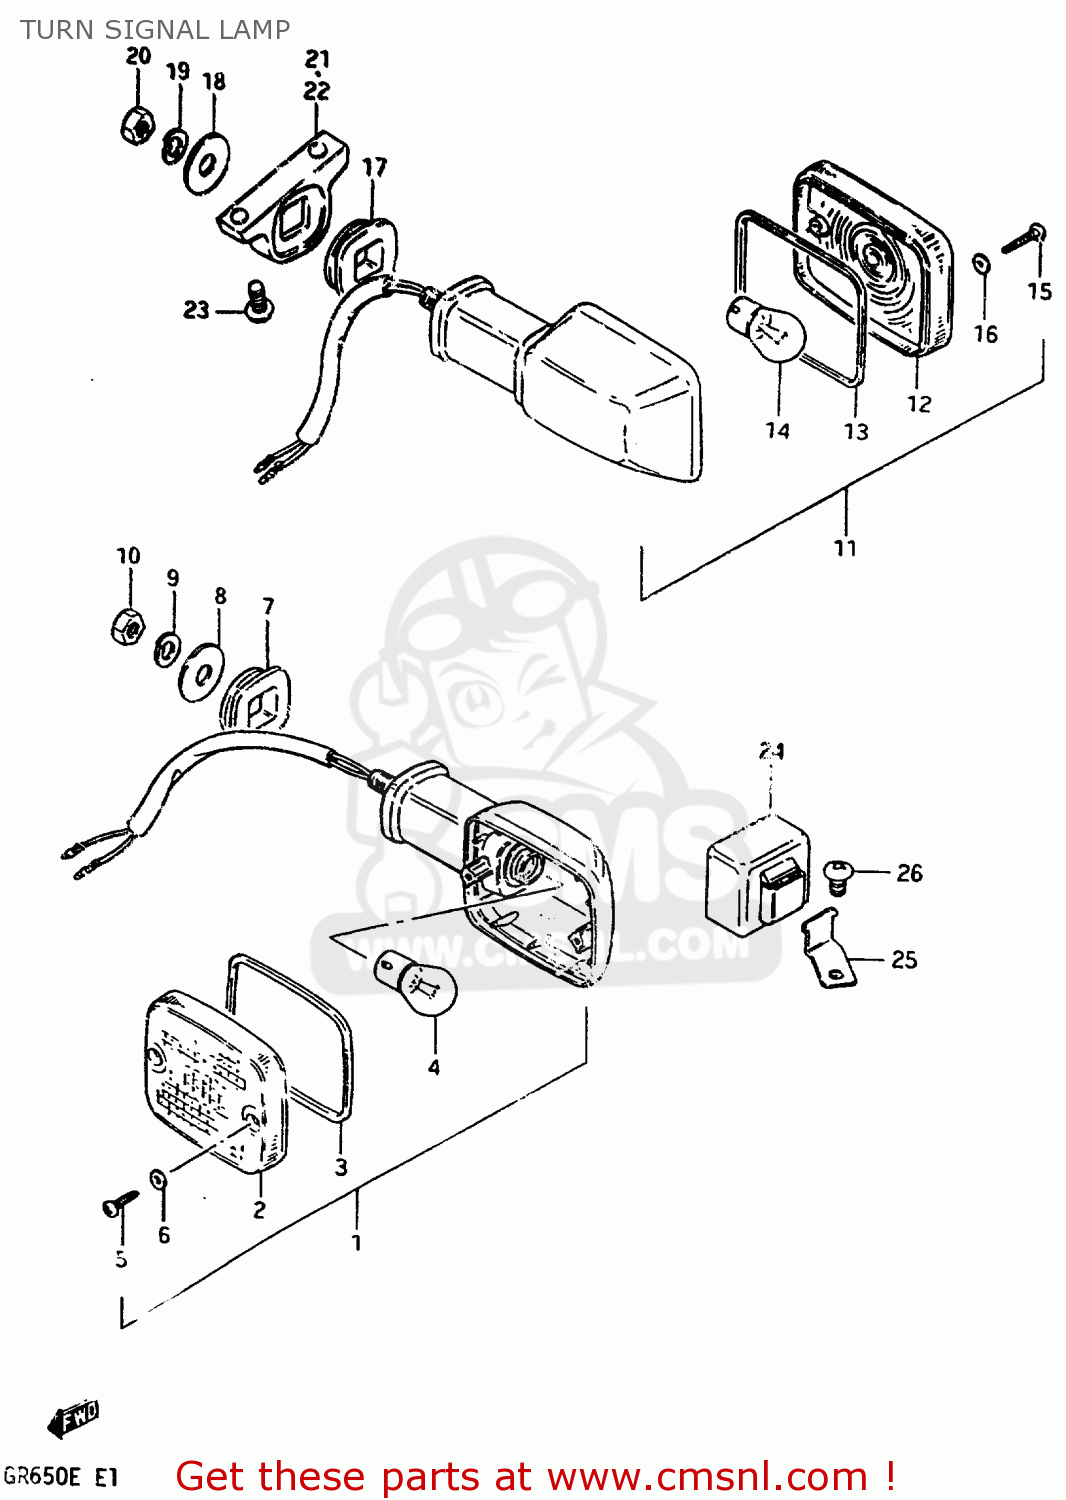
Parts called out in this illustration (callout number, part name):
1	LAMP ASSEMBLY,FRONT TURN SIGNAL
2	LENS
3	GASKET (NAS)
4	BULB(12V23W,STANLEY,A4577A)
5	SCREW
6	GASKET (NAS)
7	CUSHION
8	WASHER (10.5X30X2.3)
9	LOCK WASHER
10	NUT
11	LAMP ASSEMBLY,REAR TURN SIGNAL
12	LENS
13	GASKET (NAS)
14	BULB(12V23W,STANLEY,A4577A)
15	SCREW
16	GASKET (NAS)
17	CUSHION
18	WASHER (10.5X30X2.3)
19	LOCK WASHER
20	NUT
21	BRACKET,REAR TURN SIGNAL
22	BRACKET,REAR TURN SIGNAL
23	SCREW
24	RELAY,TURN SIGNAL
25	BRACKET,TURN SIGNAL RELAY
26	SCREW
